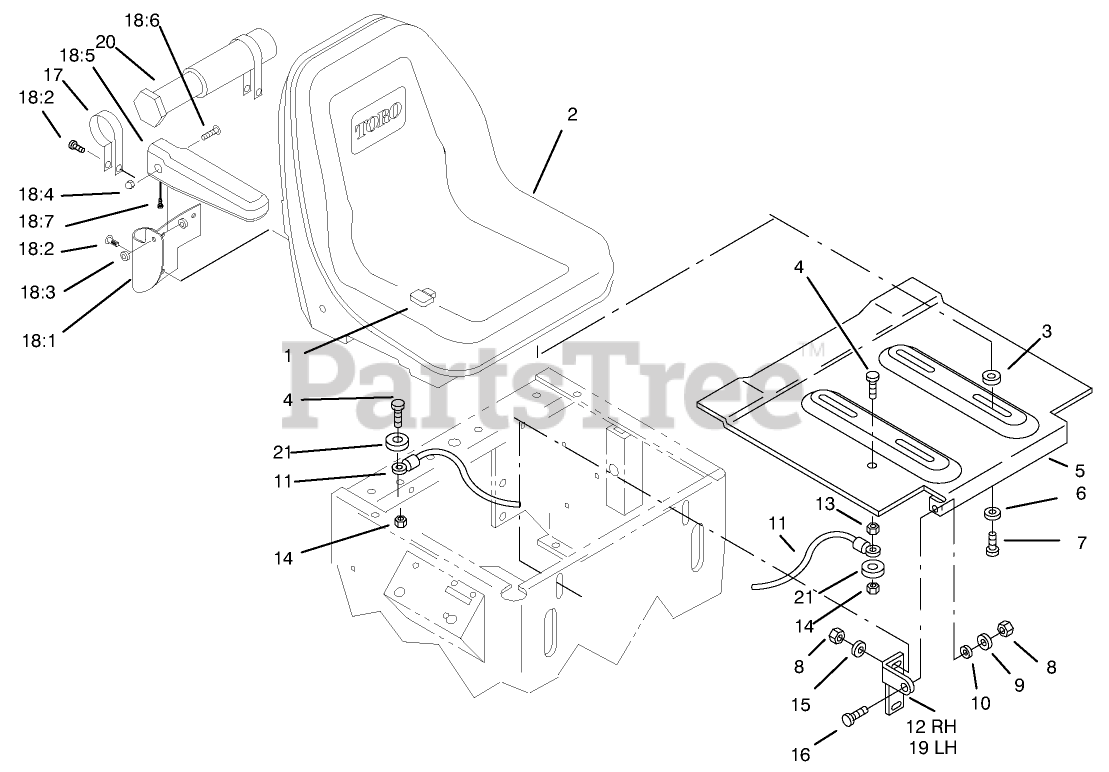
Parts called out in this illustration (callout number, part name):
1	SWITCH-SEAT
2	SEAT - GRAY
3	SPACER-NYLON
4	SCREW-HH
5	Seat Plate ASM
6	WASHER-PLAIN
7	SCREW-HH
8	NUT-LOCK, NI
9	WASHER-FLAT
10	Spacer
11	Cable
12	BRKT-SEAT PIVOT R
13	NUT-HEX
14	NUT-LOCK, NI
15	WASHER-FLAT
16	BOLT-CARR
17	TUBE-MANUAL
18	KIT-ARMREST
18:1	LH ARM BRACKET
18:1	RH ARM BRACKET
18:2	3/8-16 X 5/8 SCREW
18:3	NYLON SPACER
18:4	3/8-16 ACORN LOCKNUT
18:5	ARMREST
18:6	3/8-16X1-1/2 SCREW
18:7	3/8-16 X 3/4 SCREW
19	BRKT-SEAT PIVOT L
20	CLAMP-R
21	WASHER-FLAT
